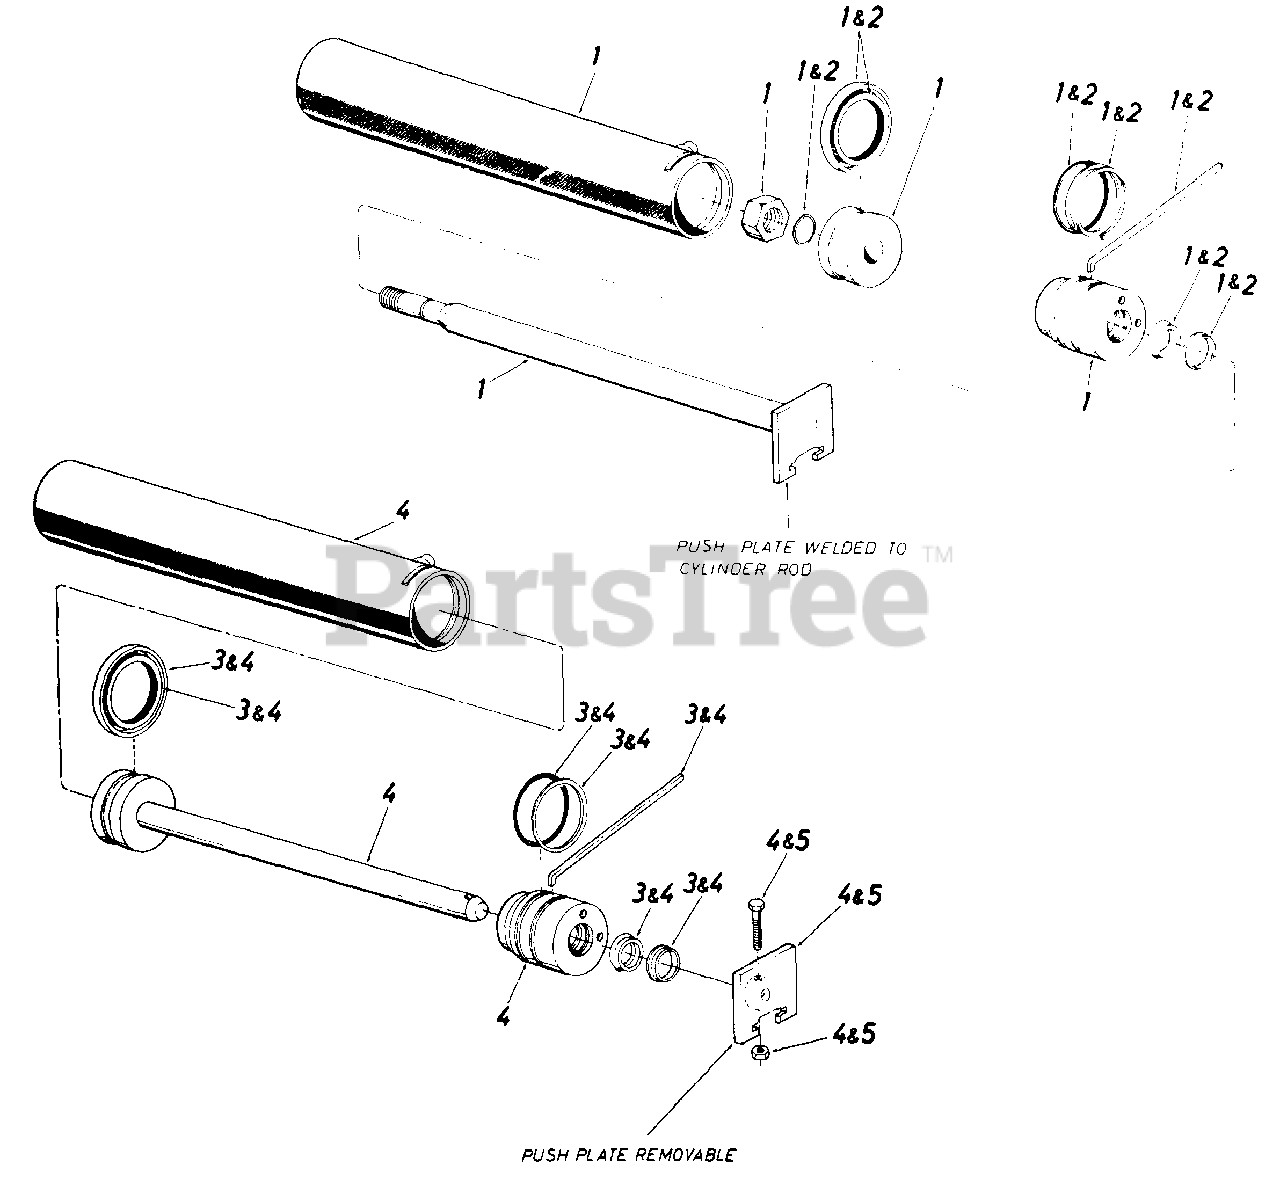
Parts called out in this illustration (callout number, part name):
1	Cylinder Ass'y. Comp.
2	3-1/2" Cyl. Kit "O"-Ring Set
3	3-1/2" Cyl. Kit "O"-Ring Set
4	Cylinder Ass'y. Comp.
5	3-1/2" Cyl. Push Plate Kit
